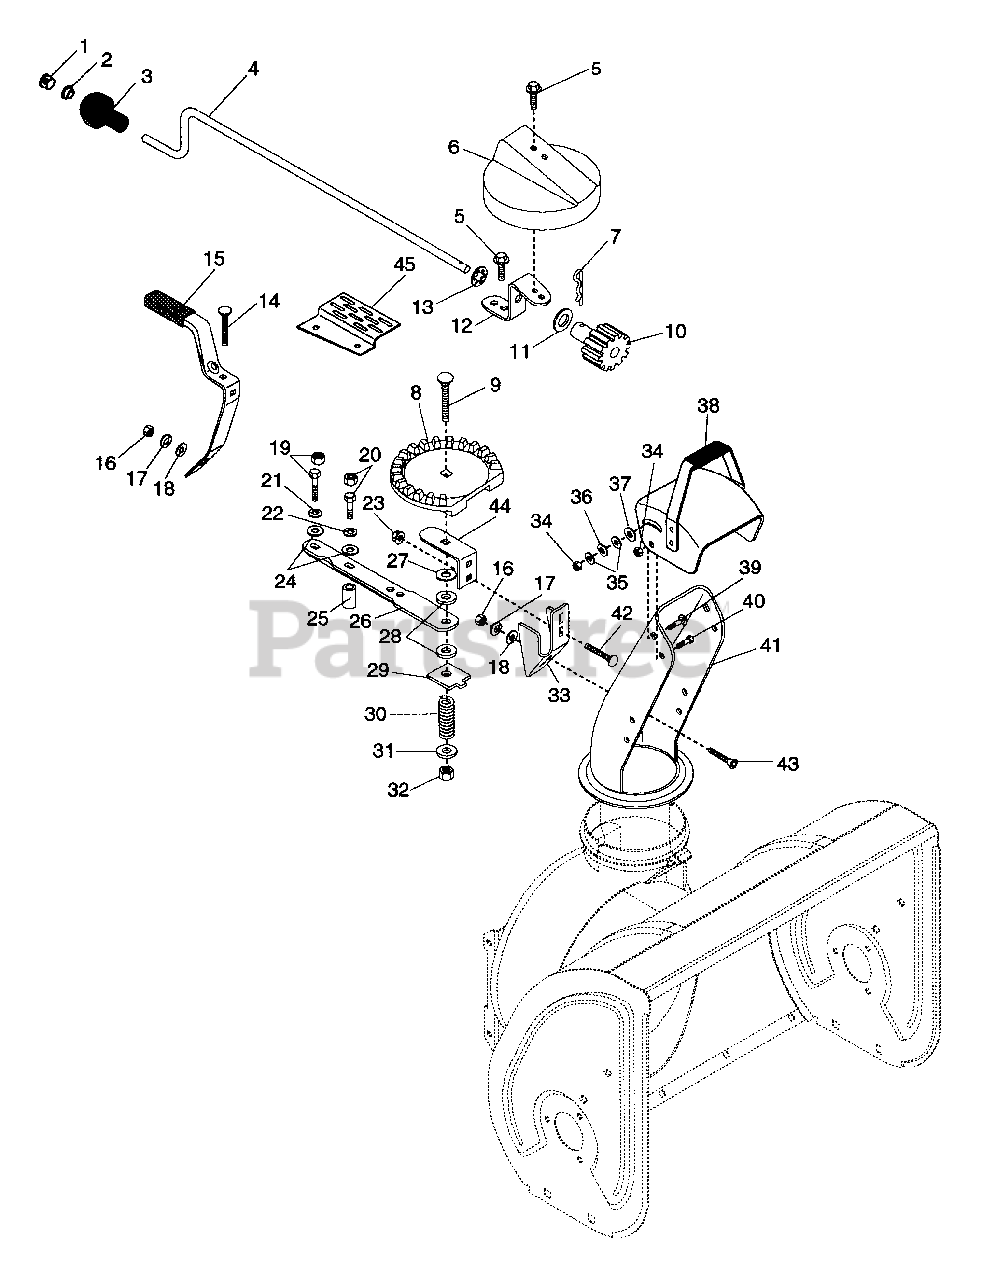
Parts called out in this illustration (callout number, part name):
1	HOLE PLUG
2	RG-RTNG-EXT .375X.010
3	KNOB
4	CHUTE CRANK
5	SCR-TAP .250-20X.50 HXSLHDPL
6	GEAR COVER
7	PIN-HAIR INT .08X.38X1.42 YWZC
8	CHUTE GEAR
9	BLT-RDHDSQNK .38-16X2.25 SHTPL
10	PINION-CHUTE
11	WSHR-FL-STL .630X1.005X.062 PL
12	BRACKET-GEAR
13	PUSHNUT .625
14	BLT-RDHDSQNK .38-16X2.00 SHTYW
15	CHUTE HANDLE W/PLASTISOL
16	NUT-HEX .250-20 PL
17	WSHR-LK .250X.077 HVY PL
18	WSHR-FL-STL .380X.875X.179 PL
19	BLT-HEX .31-18X.63 PL GR 2
19	BLT-HEX .31-18X1.25 PL GR5
19	NUT-HEX .312-18
19	NUT-LK .312-18 GR A PL
20	BLT-HEX .25-20X1.50 PL GR5
20	BLT-HEX .31-18X1.25 PL GR5
20	NUT-HEX .312-18
20	NUT-LK .312-18 GR A PL
21	WSHR-LK .312X.097 PL HVY
22	WSHR-LK .250X.077 HVY PL
22	WSHR-LK .312X.097 PL HVY
23	NUT-LK-FLG .250-20 PL
24	WSHR-FL-STL .328X.875X.062 PL
25	SPACER .280X.625X.760
25	SPACER .280X.625X.640
25	SPACER .322X.626X.50
26	STRAP
26	STRAP-CHUTE CONTROL
26	STRAP-DISCHARGE CHUTE SUPPORT
27	WSHR-FL-STL .380X1.50X.062 PL
28	FRICTION WASHER
29	FRICTION PLATE
30	SG-COMP .187X.56X1.62
31	WSHR-FL-STL.406X.812X.065PL
32	NUT-LK-CTR .375-16 GR A PL
33	STRAP, CHUTE
34	NUT-LK .312-18 GR A PL
35	WSHR-FL-STL .323X.625X.062 PL
36	WAVE WASHER .390X.655X.110
37	WSHR-PLASTIC .390X.875X.062
38	DEFLECTOR W/DECAL
39	BLT-RDHDSQNK .31-18X.75 SHT PL
40	BLT-HEX .31-18X.50 PL GR2
41	DISCHARGE CHUTE
41	CHUTE-DISCHARGE
42	BLT-RDHDSQNK .25-20X.62 PL
43	SCR-SKH .25-20X.75 FLTCNTRSK
44	GEAR STRAP
45	MUFFLER SHIELD
